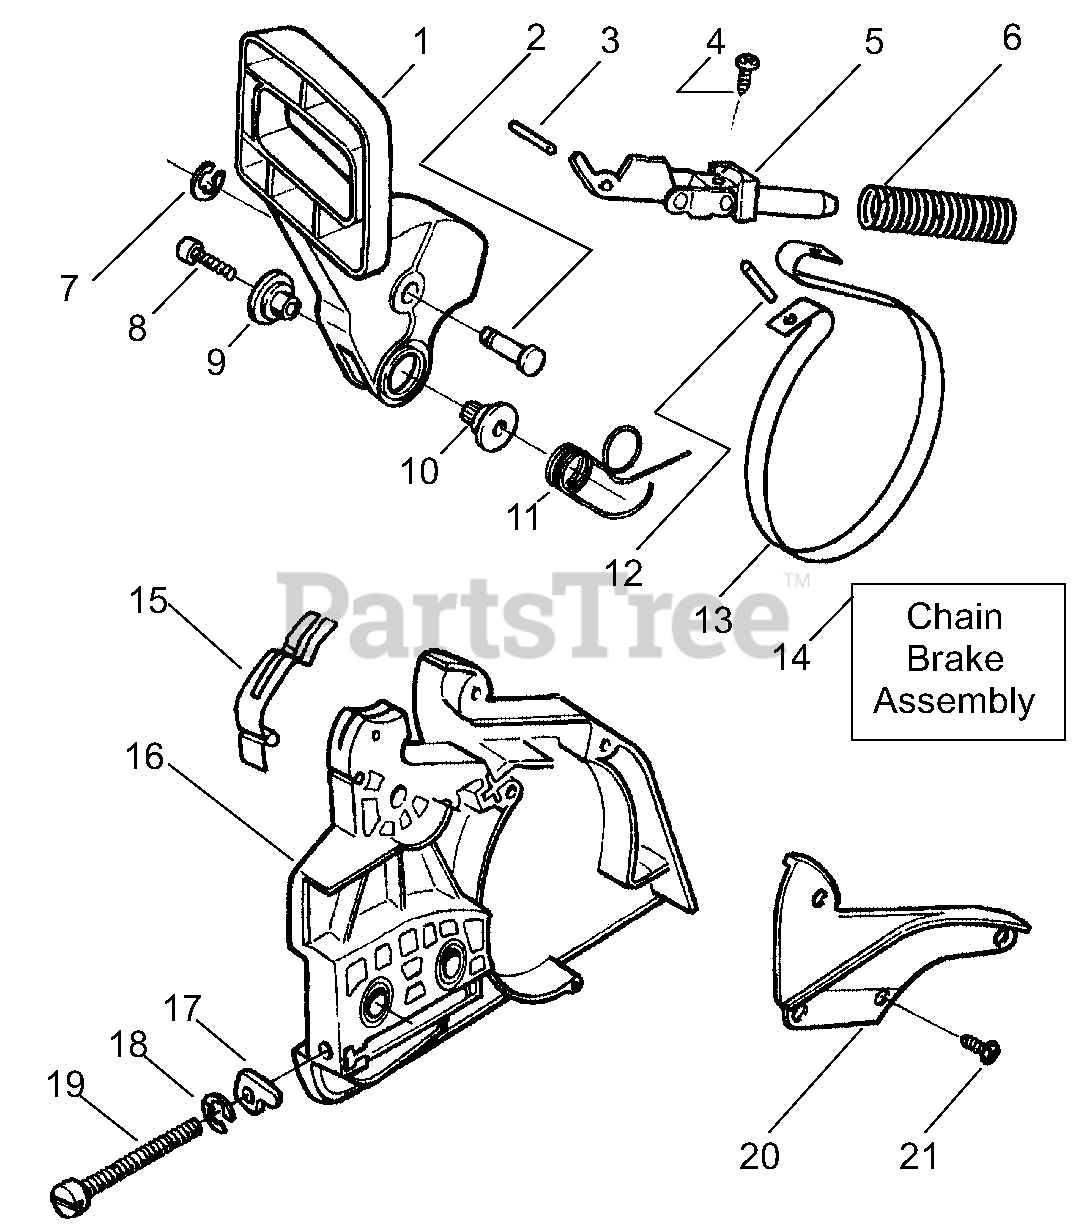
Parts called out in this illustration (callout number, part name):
1	Kit- Lever & Link Assy.
4	Screw
5	Assy-Front Link
6	Spring-Chain Brake
9	Journal-Right
10	Journal-Left
11	Spring-Handguard
12	Pin-Spring
13	Band-Brake
14	Assy-Chain Brake
15	Spring-Position
16	Cover-Clutch
17	Pin-Bar Adjusting
19	Screw-Bar Adjusting
20	Cover-Chain Brake Spring
21	Screw
